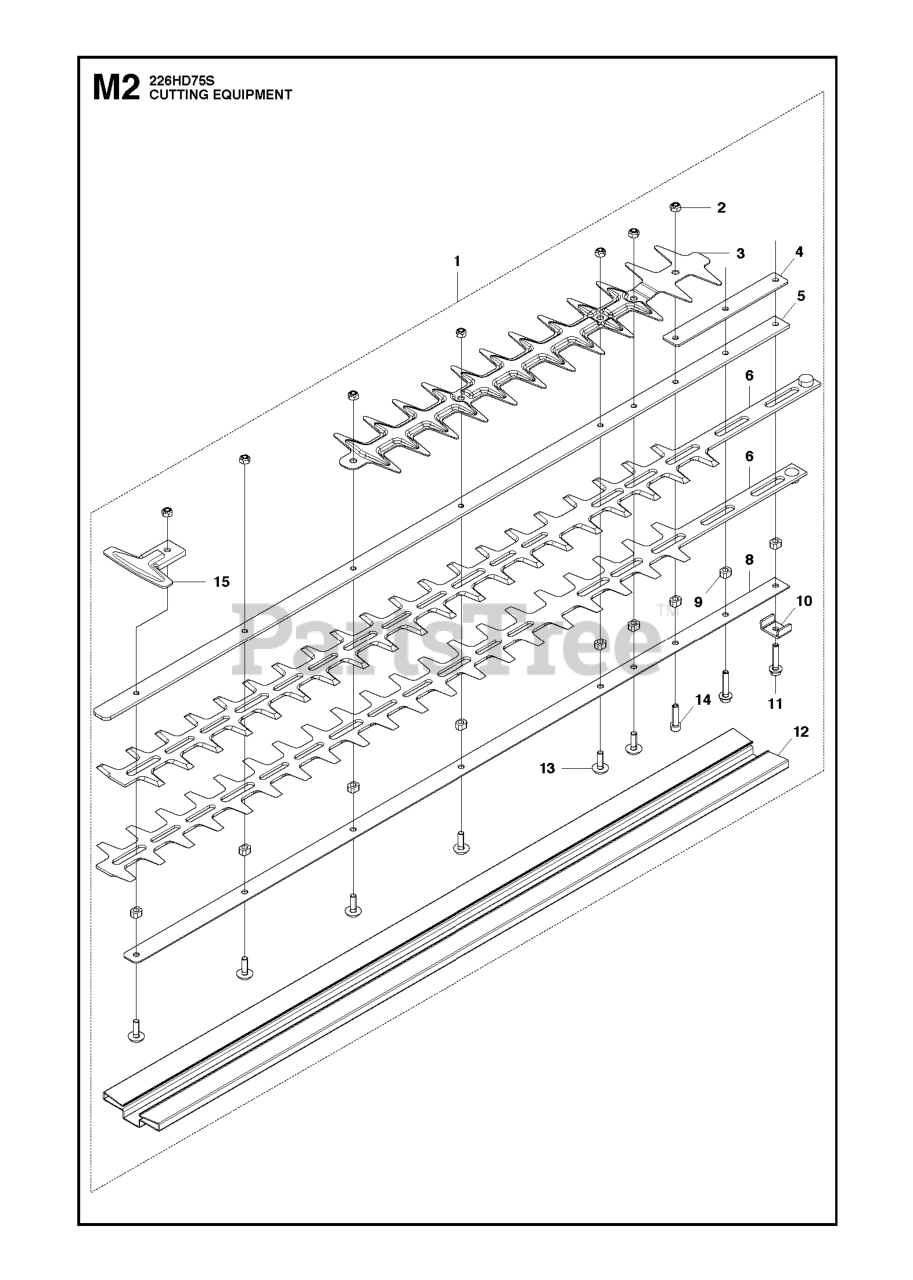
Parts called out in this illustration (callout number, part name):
1	BLADE
1	BLADE ASSY 226HD75S
3	BLADE GUARD
5	PLATE UPPER
6	BLADE 226HD75S
8	PLATE LOWER
11	BOLT
13	SCREW
13	BOLT
14	BOLT
15	COVER TOP PROTECTION
